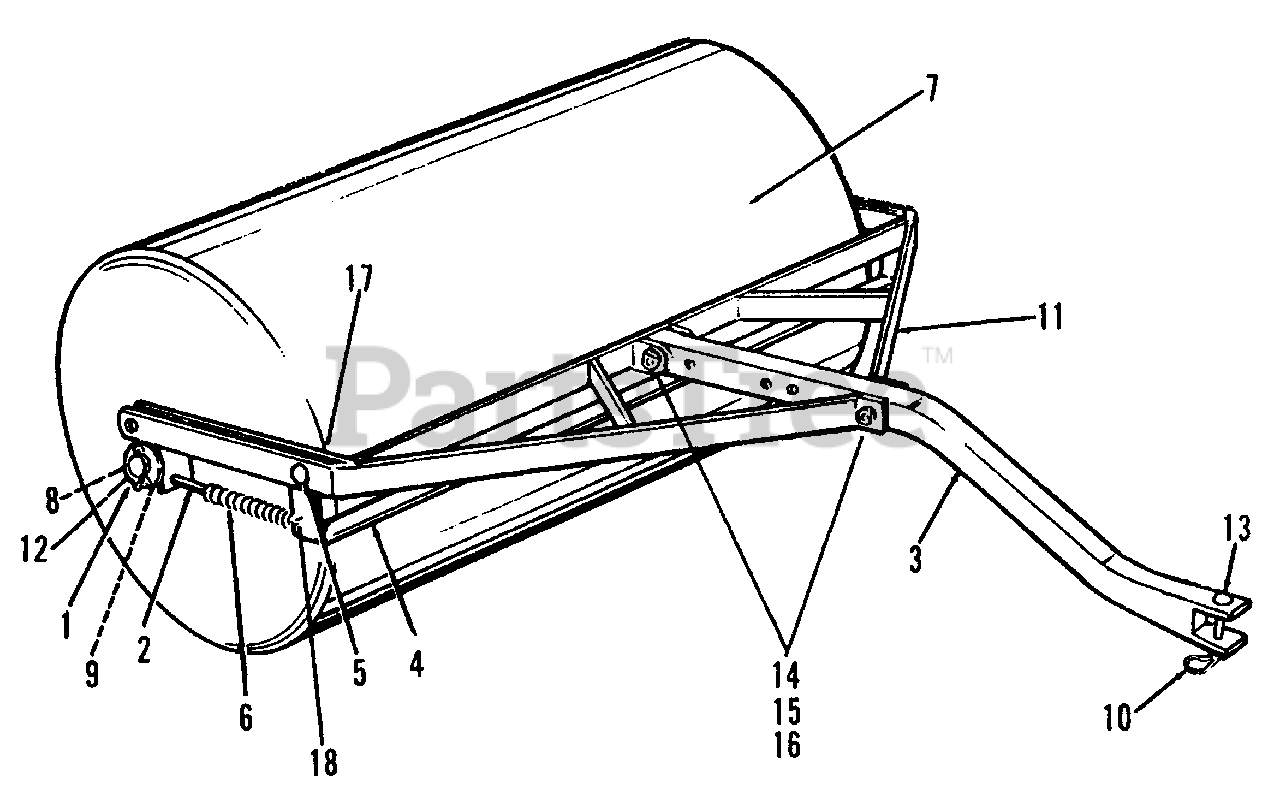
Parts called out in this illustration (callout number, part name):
1	Plain Washer, 3/4"
2	Extension Pin
3	Tongue Assembly
9	Bearing Retainer
10	Spring Clip
11	Frame Assembly
12	Cotter Pin, 3/32" x 1" lg.
13	Pin
14	Hex Capscrew, 3/8"-16 x 2-1/4" lg.
15	Lock Washer, 3/8"-16
16	Hex Nut, Full, 3/8"-16
17	Cotter Pin, 3/32" x 5/8" lg.
18	Cotter Pin, 1/8" x 1/2" lg.
